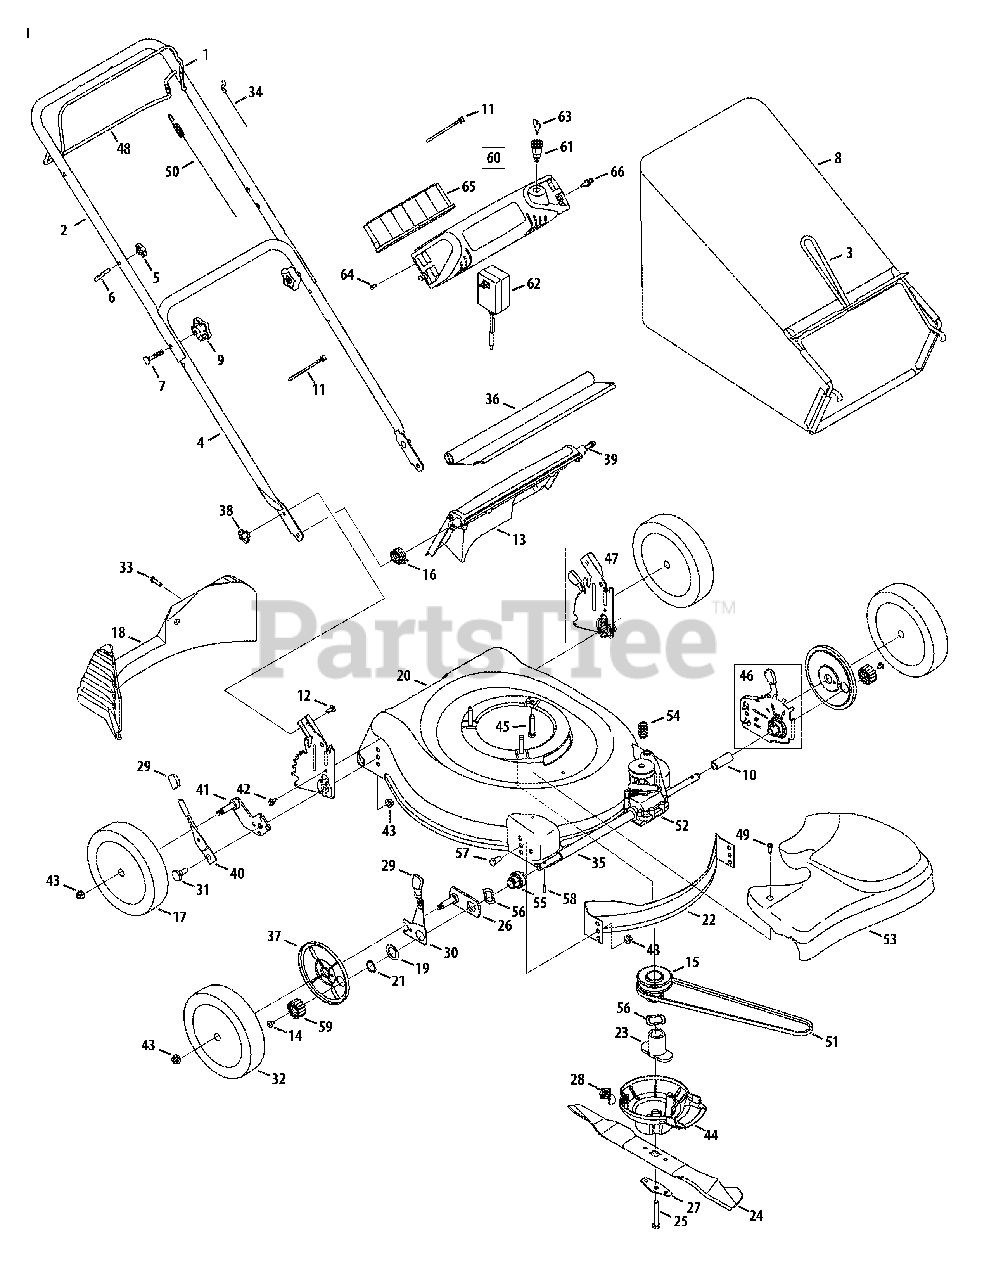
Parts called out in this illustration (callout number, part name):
1	Blade Control
4	Lower Handle
5	Wing Nut
6	Rope Guide
7	Carriage Bolt ,5/16-18 x 2
8	Grass Bag Assembly
9	Hand Knob
10	Sleeve Spacer - LH
11	Cable Tie
12	Carriage Bolt ,1/4-20
13	Rear Discharge Door
14	Screw 1/4-20
15	Drive Pulley Assembly
16	Torsion Spring - RH
17	Rear Wheel, 8" x 1.8"
18	Rear Baffle
19	Washer, 1.5" OD
20	Deck - 21"
21	Snap Ring
22	Front Baffle
23	Blade Adapter
24	21" Mulch Blade
25	Hex Bolt , 3/8-24 x 2.5
26	Pivot Plate Assembly
27	Blade Bell Support
28	Engine Baffle Bracket
29	Adjustment Lever Knob
30	Front Lever - RH
30	Front Lever - LH
31	Shoulder Screw
32	Front Wheel, 8" x 1.8"
33	Screw, 1/4-15 x 1.000
34	Control Cable - 40.75"
35	Sleeve Spacer - RH
36	Trailshield
37	Wheel Dust Cap
38	Wing Nut, 1/4-20
39	Rear Door Pivot Rod
40	Spring Lever
41	Pivot Arm Assembly - RH
41	Pivot Arm Assembly - LH
42	AB Screw
43	Flange Lock Nut, 3/8-16
44	Engine Baffle
45	TT Sems Screw, 3/8-16 x 1.00
46	Ht. Adj. Assy. Front - LH
46	Ht. Adj. Assy. Front - RH
47	Rear Handle Bracket Assy. - LH
47	Rear Handle Bracket Assy. - RH
48	Drive Control
49	Shoulder Screw
50	Drive Cable
51	V-Belt
52	Transmission Assembly
53	Front Drive Cover
54	Belt Tension Spring
55	Bearing Assembly
56	Wave Washer
57	Hex Screw
58	Dowel Pin
59	Gear, 14T - RH
59	Gear, 14T - LH
60	Electric Start Harness Assembly
61	Key Switch
62	Battery Charger 12V
63	Key
64	Screw, #10-16 x .75
65	12 Volt Battery
66	Plastic Rivet
